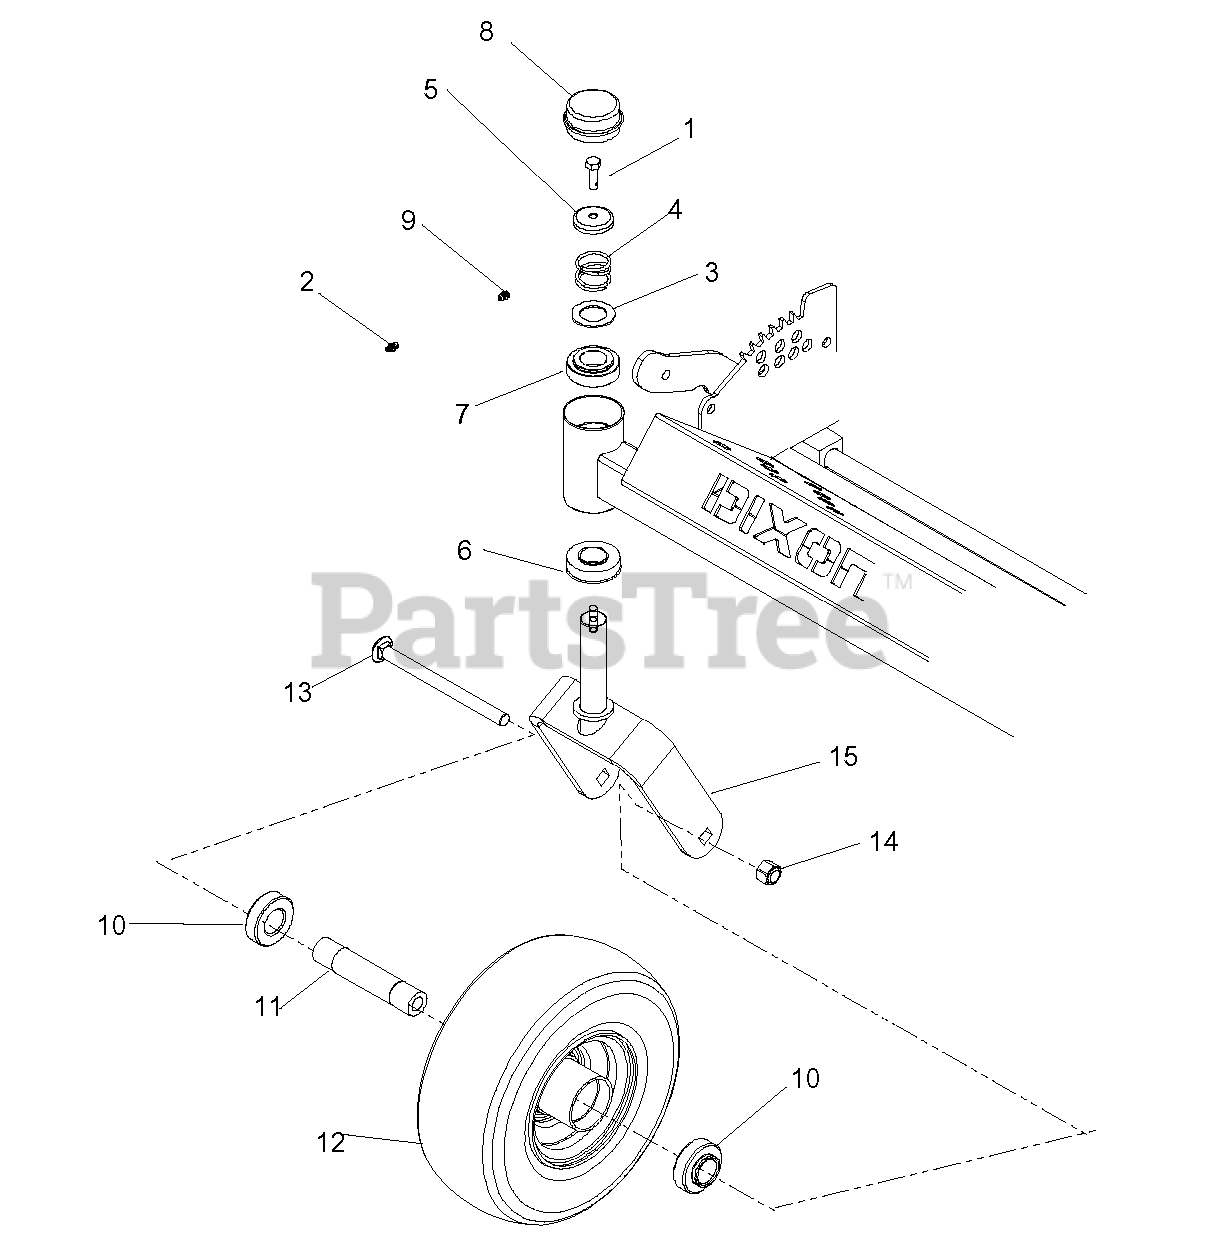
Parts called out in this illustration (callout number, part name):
1	5/16-18X1 HHB G5W/NY
2	ZERK, 3/16, DRIVE IN
3	WASHER, 1.025 ID X 1.64
4	SPRING, CASTER
5	CASTER.PLUG
6	BEARING
7	BUSHING, CASTER
8	DUST CAP
9	GREASE ZERK-1/4"
10	BEARING-ECC LOCK
12	CASTER WHEEL AND TIRE
13	RHSNB 1/2-13 X 6.50 GR2 ZD
14	NUT, HEX 1/2-13 W/NYLOK
15	CASTER DK BLUE
